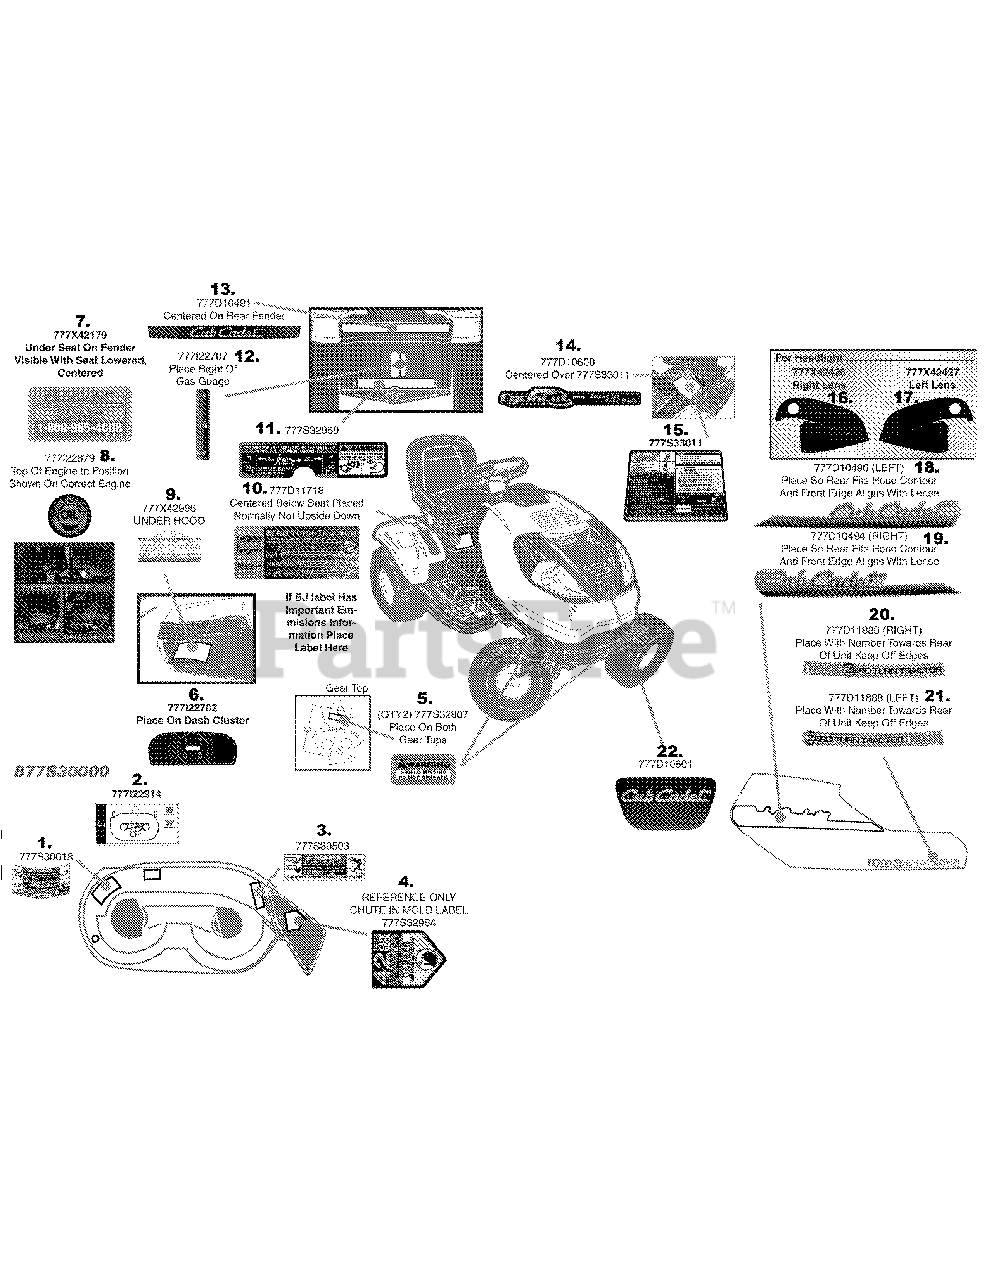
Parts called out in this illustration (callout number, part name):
1	LABEL-DECK SAFETY
2	LABEL-ZTT I1042 DECK ROUTE
3	LABEL-DANGER CHUTE
4	LABEL:RDRCHT:DNGCUT:42CUB
5	LABEL-SAFETY:I1000 SHIELD
6	LABEL-RIDER:DASH CUB Z1000
7	LABEL-CUB HOTLINE
8	LABEL-CHECK ENG OIL
9	LABEL-RIDER PARTS LIST ZTT I1042
10	LABEL-ZTT I1000 LOW TAC
11	LABEL-SAFETY I1000 TRANS RELEASE
12	LABEL-RIDER:FUEL LEVEL IND CUB
13	LABEL-RIDER:FENDER TIME SAVERZ
14	LABEL-RIDER:CUB 50 I1000 DECK
15	LABEL-ZTT I1042 TRANSMISSION COVER
16	LABEL-RIDER:RT51:LENS DR LFT
17	LABEL-RIDER:RT51:LENS DR RT
18	LABEL-RIDER:HOOD TIME SAVERZ LT
19	LABEL-RIDER:HOOD TIME SAVERZ RT
20	LABEL-ZTT I1042 LEFT NUMBER
21	LABEL-ZTT I1042 RIGHT NUMBER
22	LABEL-RIDER:FUEL LEVEL IND CUB
